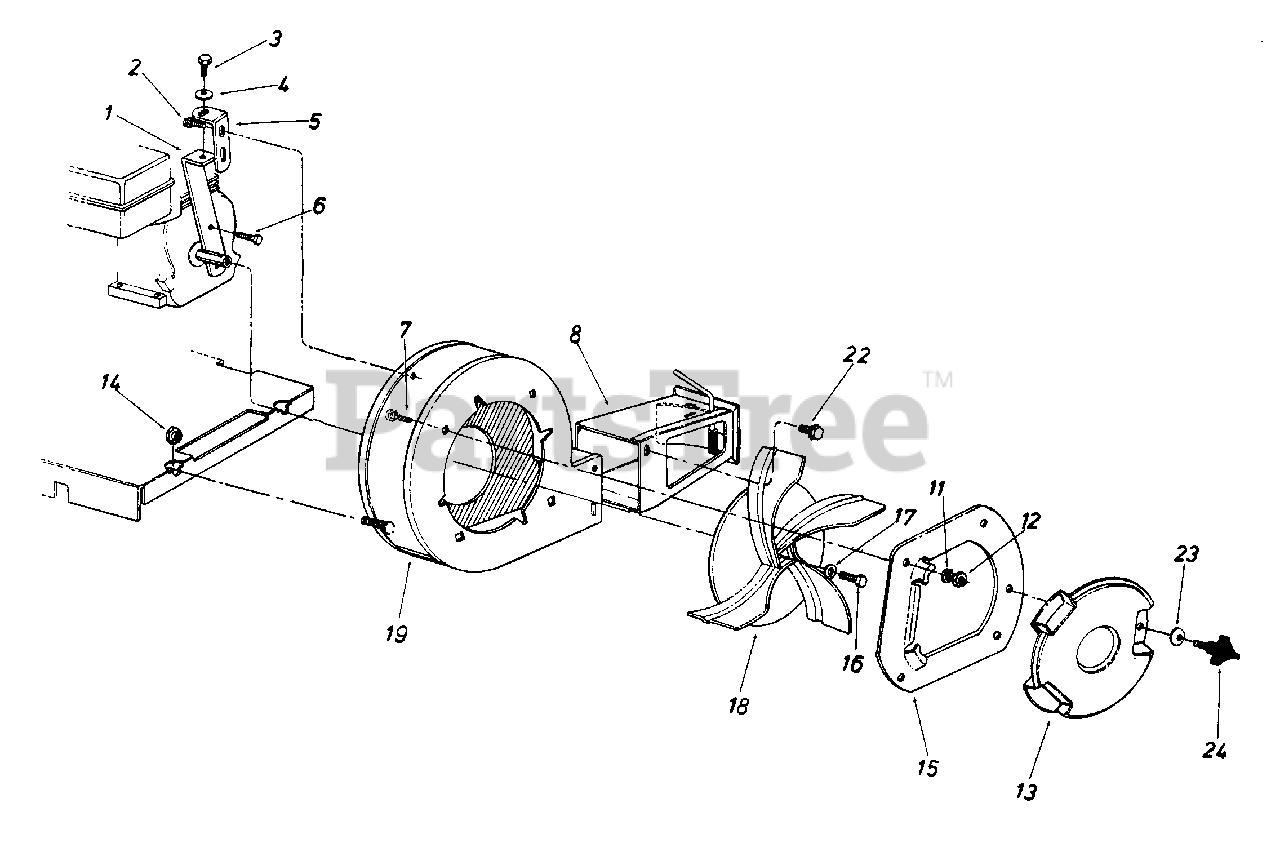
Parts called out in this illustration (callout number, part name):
3	Hex Bolt 5/16-18 x .75" Lg.
4	L-Wash. 5/16" I.D.
7	Carriage Bolt 5/16-18 x .62"
12	Hex Nut 5/16-18 Thd.
13	Blower Guard
14	Hex Shoulder Nut .50" I.D.
15	Nozzle Plate Ass'y.
16	Hex Bolt 3/8-24 x 1.25"
17	L-Wash. 3/8" I.D. - H.D.
23	Bell-Wash. .34" I.D. x .87" O.D.
24	3-Arm Thumb Scr .5/16-18 x .75" Lg.
14496A-0637	HOUSING ASM-BLOWER - POWDER BLACK (0637)
14496A-0638	HOUSING ASM-BLOWER - MTD/TROY-BILT RED (0638)
